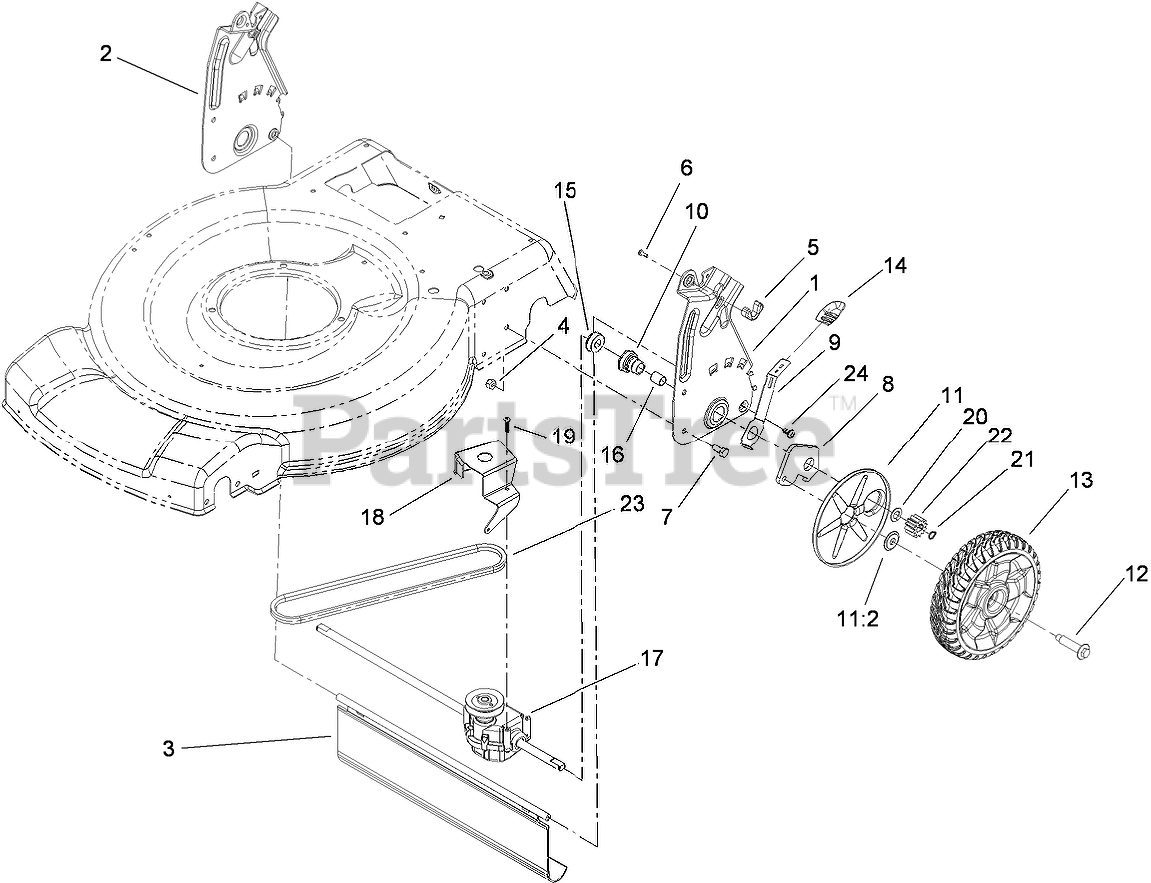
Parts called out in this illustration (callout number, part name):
1	PLATE-REAR, LH (HOC)
2	PLATE-REAR, RH (HOC)
3	SHIELD-TRAILING
4	NUT-LOCK, NI
5	ANCHOR-BAG
6	Screw-PPH
7	SCREW-HH
8	ARM-PIVOT, REAR
9	ARM-SPRING
10	RETAINER-BUSHING, HOC
11	WHEEL COVER ASM
11:1	COVER-WHEEL
11:2	WASHER-STEPPED
12	BOLT-SHOULDER
13	8 INCH WHEEL GEAR ASM
14	Knob-Lever, HOC
15	BEARING-BALL
16	BUSHING-SLEEVE
17	TRANSMISSION
18	BRACKET-TRANSMISSION
19	SCREW-PLASTITE
20	WASHER-THRUST
21	RING-RETAINING
22	GEAR-PINION
23	BELT-V
24	SCREW-PTH
